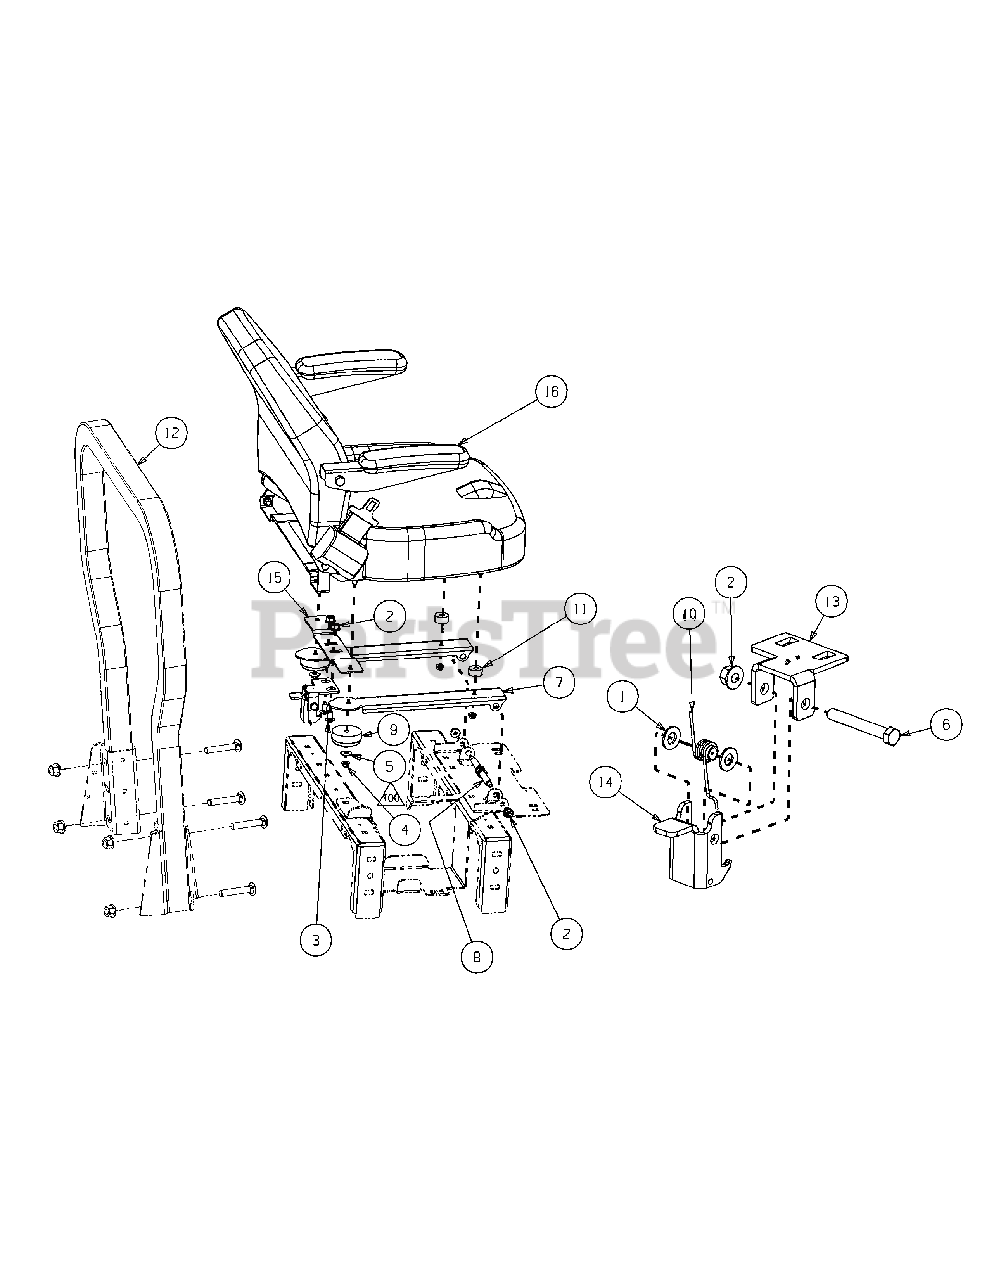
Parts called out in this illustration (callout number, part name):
1	Flat Washer, 3/8 Nylon
2	Nut, Hex 3/8-16 Flange Lock
3	Carriage Bolt, 3/8-16 x .75
4	Nut, Hex 5/16-18 Flange Lock
5	Washer, .325 x .930 x .045
6	Hex Cap Screw 3/8-16 x 2.75
7	Mounting Bracket, Seat
8	Shoulder Screw, .50x2.345, 3/8-16
9	Grommet, 2.5 OD x 1.0 Long
10	Deck Lift Spring, Left Hand
11	Spacer, .406 ID x 1.00 OD x .38
12	Rops Assembly includes:
15	Seat Latch Bracket
